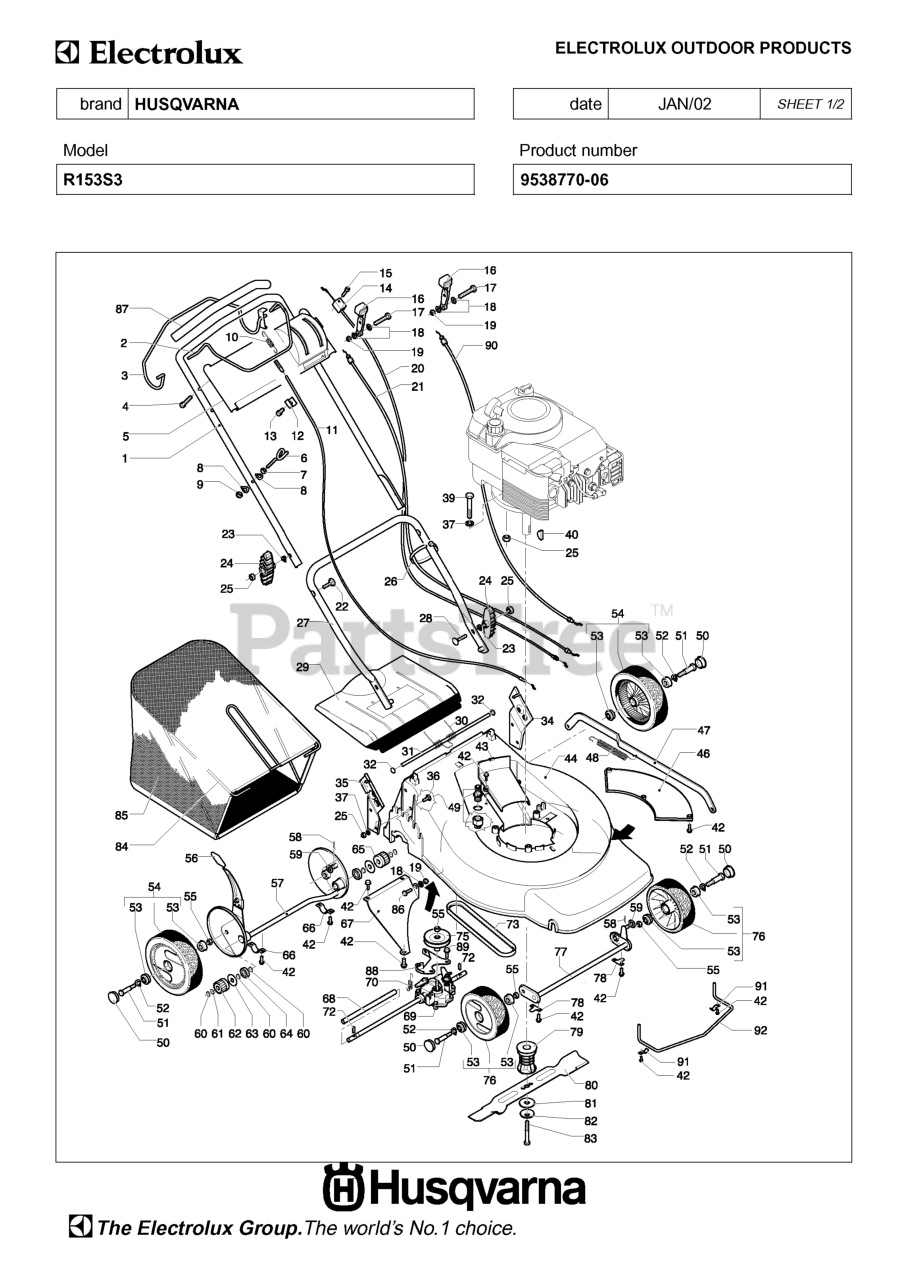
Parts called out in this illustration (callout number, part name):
28	Screws
42	Screws
58	Pins
60	Washers
